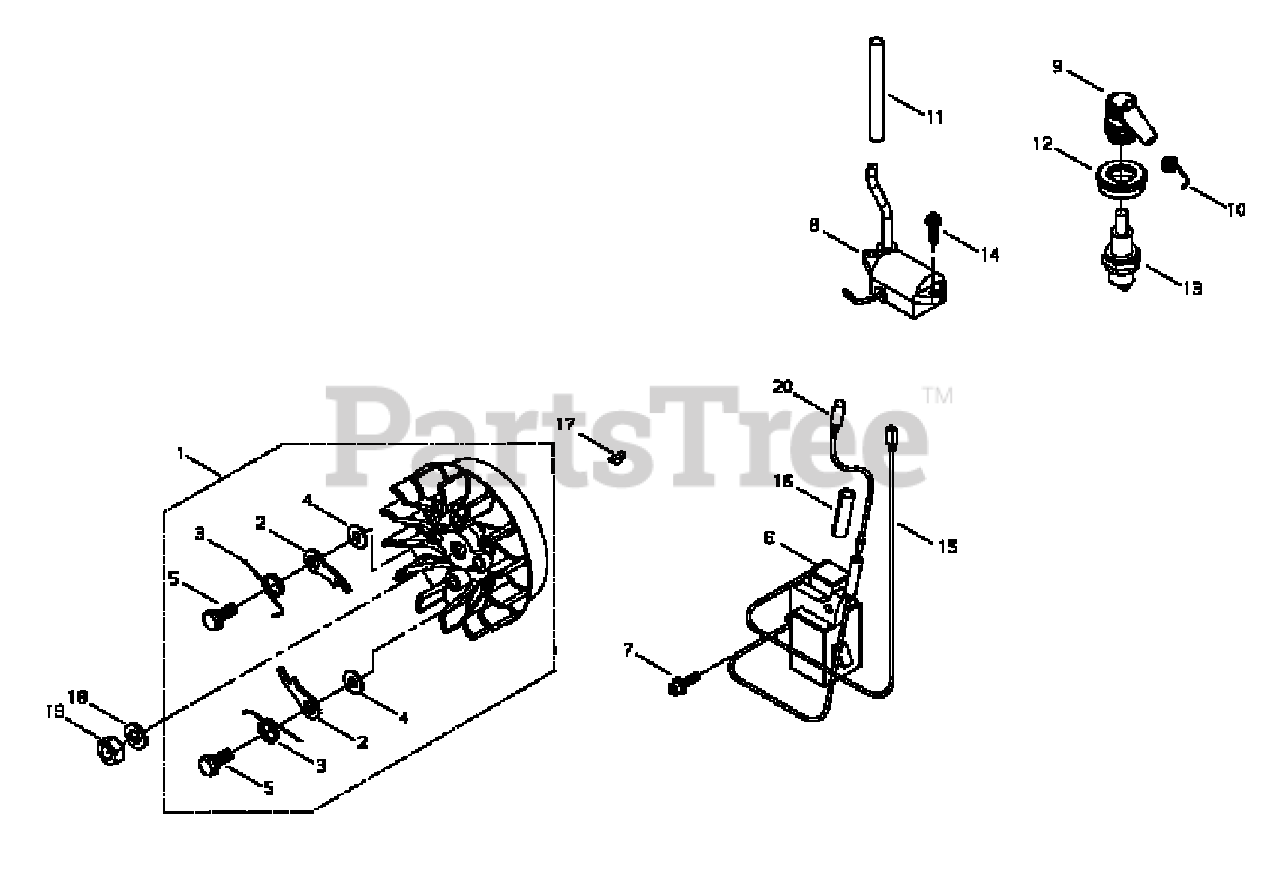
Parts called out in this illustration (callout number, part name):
1	FLYWHEEL
2	RATCHET
3	SPRING, RATCHET
4	WASHER 6 MM
5	BOLT
6	COIL, EXCITER
7	BOLT M4×20
8	COIL, IGNITION
9	CAP, SPARK PLUG
10	TERMINAL, SPARK PLUG
12	SEAL, SPARK PLUG
13	SPARK PLUG - BPMR7A
14	SCREW M4×16
16	TUBE
17	KEY, WOODRUFF 3×10
18	WASHER, SPRING 8
